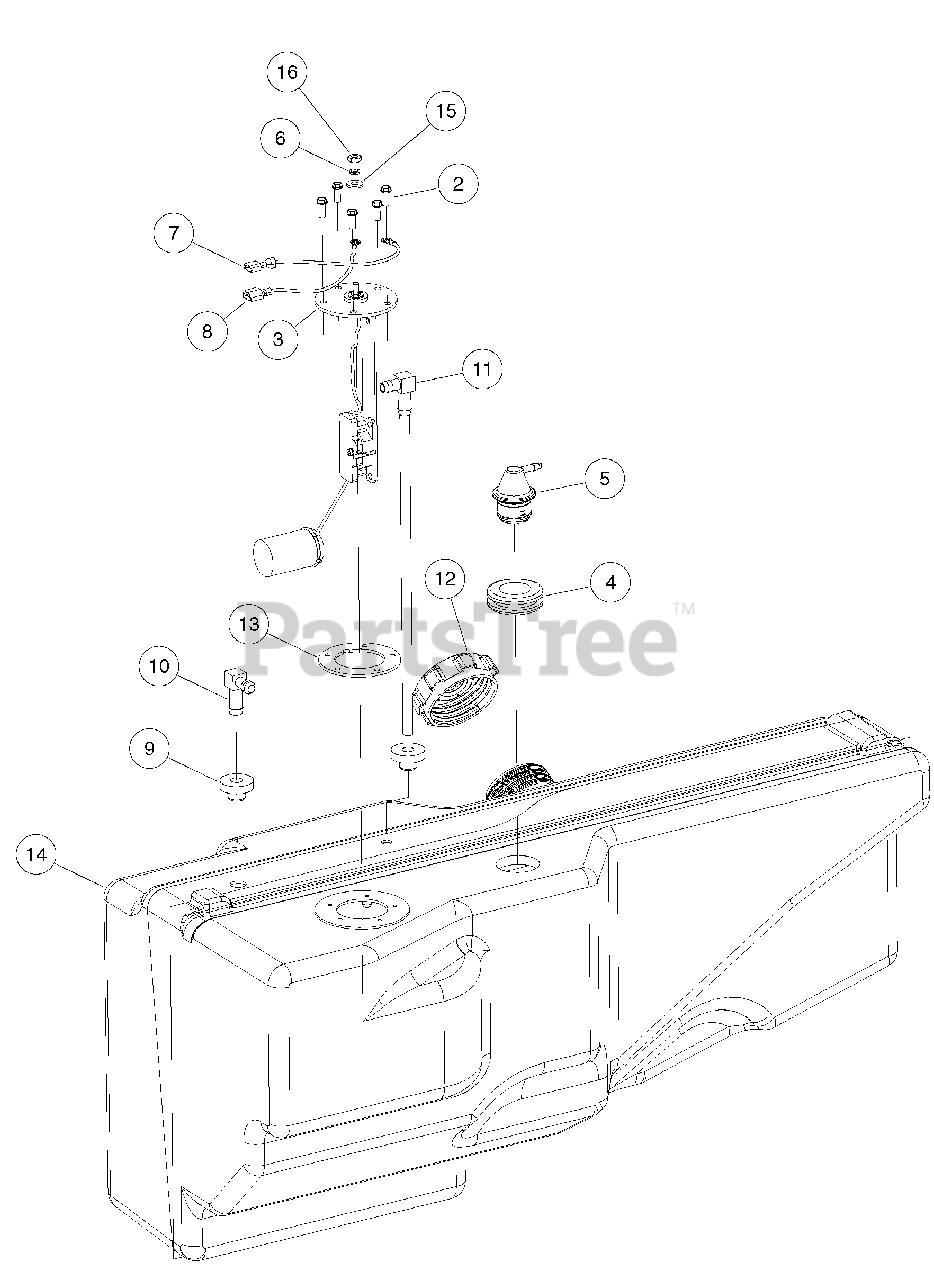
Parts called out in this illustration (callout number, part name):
1	Asm, Tank, Fuel, Diesel, 4x4
2	Screw, #10-16 Hex-Head Hi-Lo
3	Sending Unit, Fuel Level
4	Insulation Grommet
5	Vent, Fuel Tank
6	Washer, #10 Split Lock
7	Wire Asm, Blk, 170mm
8	Wire Asm, Org, 170mm
9	Bushing, Line, Return
10	Elbow, 90 Barbed
11	Pickup Tube, Fuel
12	Cap, Fuel (Diesel)
13	Gasket, Rubber
14	Tank, Fuel, Diesel, 4x4
15	Washer, #10 Type A Flat
16	Nut, #10-32 Brass Hex
